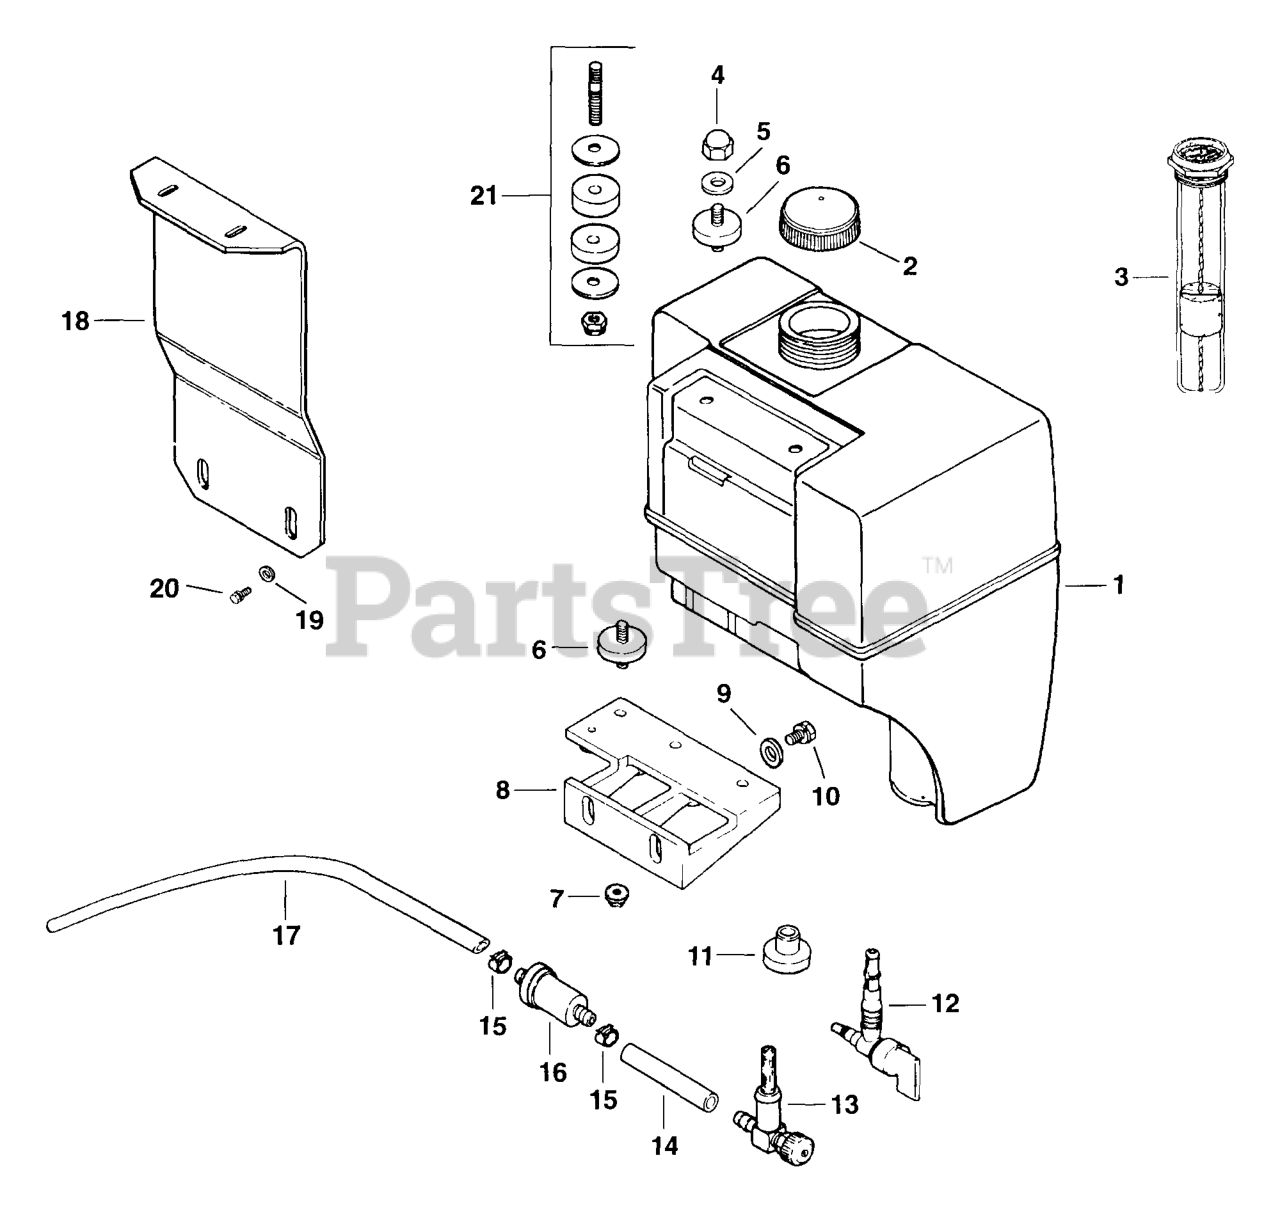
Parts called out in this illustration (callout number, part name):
1	KIT - USE 47 755 39
1	KIT, FUEL TANK
2	CAP
4	NUT - (#DSC)
5	WASHER, PLAIN 1/4"
6	KIT - USE 47 760 01
7	PALNUT, 1/4-20
10	SCREW, SEMS 3/8-16X1-1/4" - DISCONTINUED
11	BUSHING
11	BUSHING, FUEL TANK
12	VALVE, FUEL SHUT-OFF
13	VALVE
14	LINE - DISCONTINUED
15	CLAMP, HOSE
